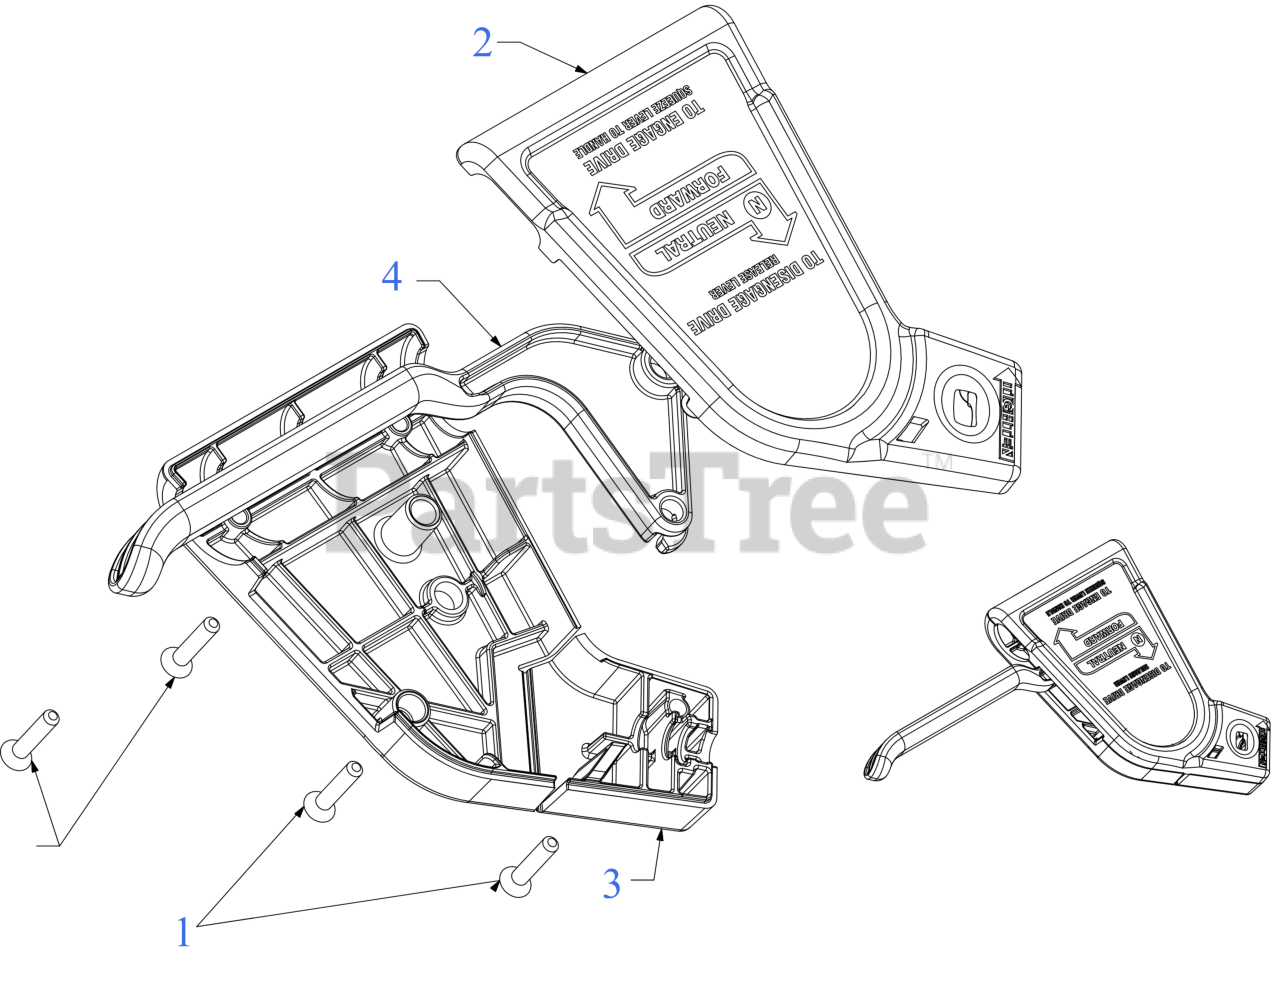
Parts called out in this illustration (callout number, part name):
1	SCREW #10-16 x 1.00
2	KIT-DRIVE CONTROL
3	SQUEEZEBOX CONTROL COVER
4	SELF PROPELLED LEVER
